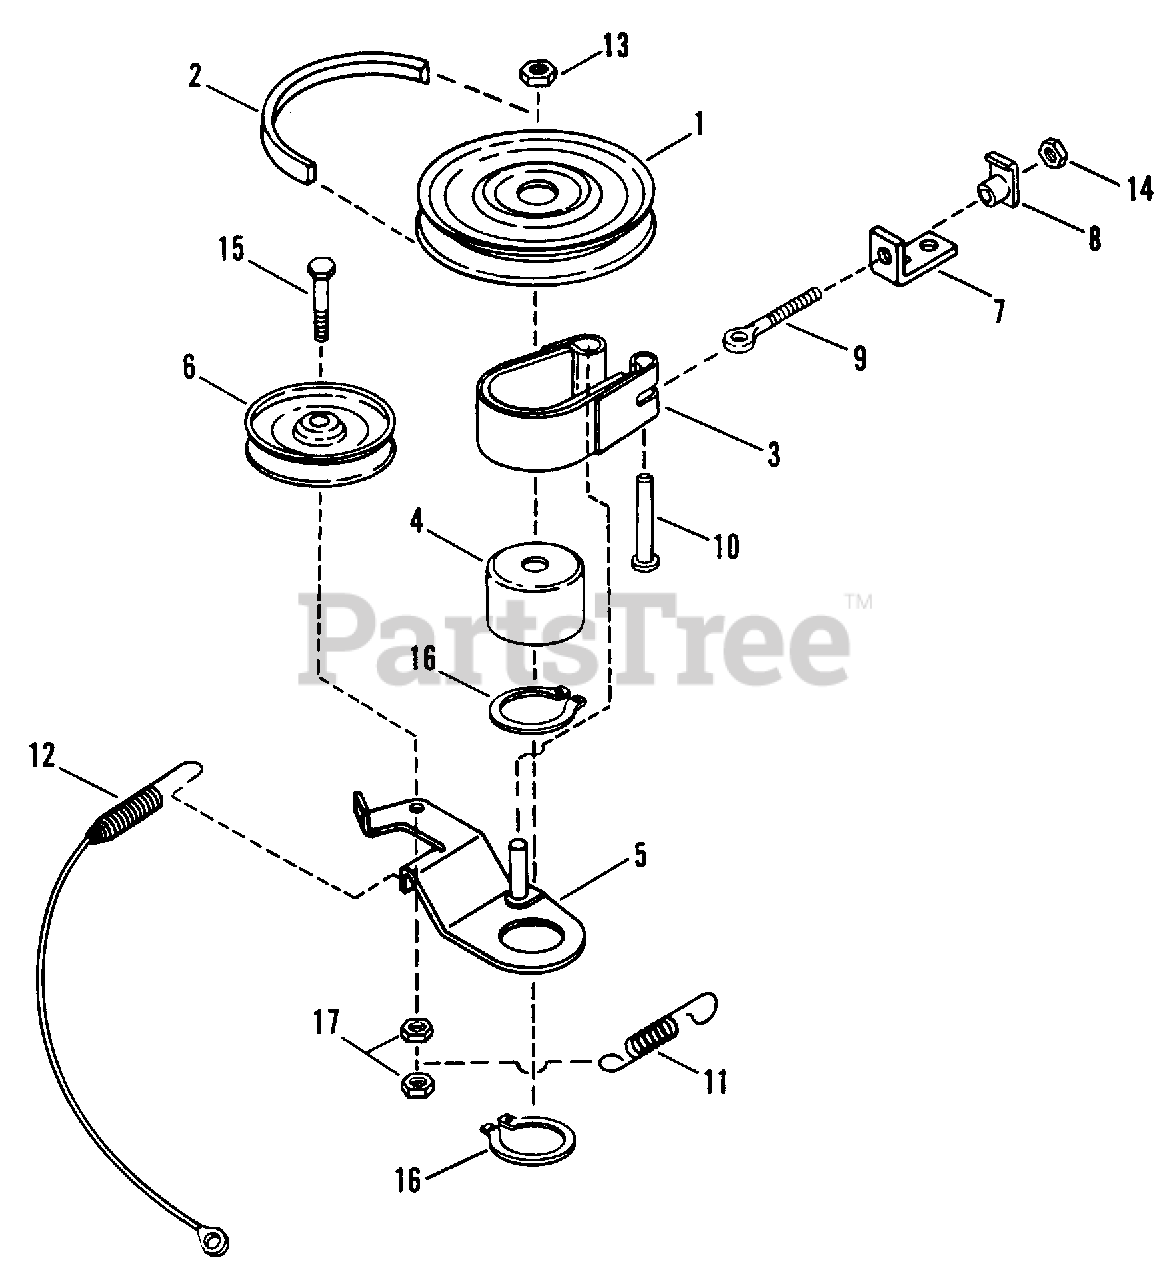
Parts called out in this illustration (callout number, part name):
1	PULLEY, Drive
2	BELT, Drive
3	BAND, Brake Assembly
4	DRUM, Brake
5	ASSEMBLY, Brake Arm
6	PULLEY, Idler
7	ANCHOR, Brake
8	NUT, 1/4-20 Tec.
9	BOLT, 1/4-20 Eye
10	PIN, Clevis, 1/4x1-1/4"
11	SPRING, Blade Brake
12	CABLE, Blade 28.5" Long
13	NUT, 3/4-16 Hex Jam
14	NUT, 1/4-20 Hex
15	SCREW, 3/8-24x2" Hex Head Cap (Gr. 5)
16	RING, 2" External Retaining
17	NUT, 3/8-24 Hex Lock
